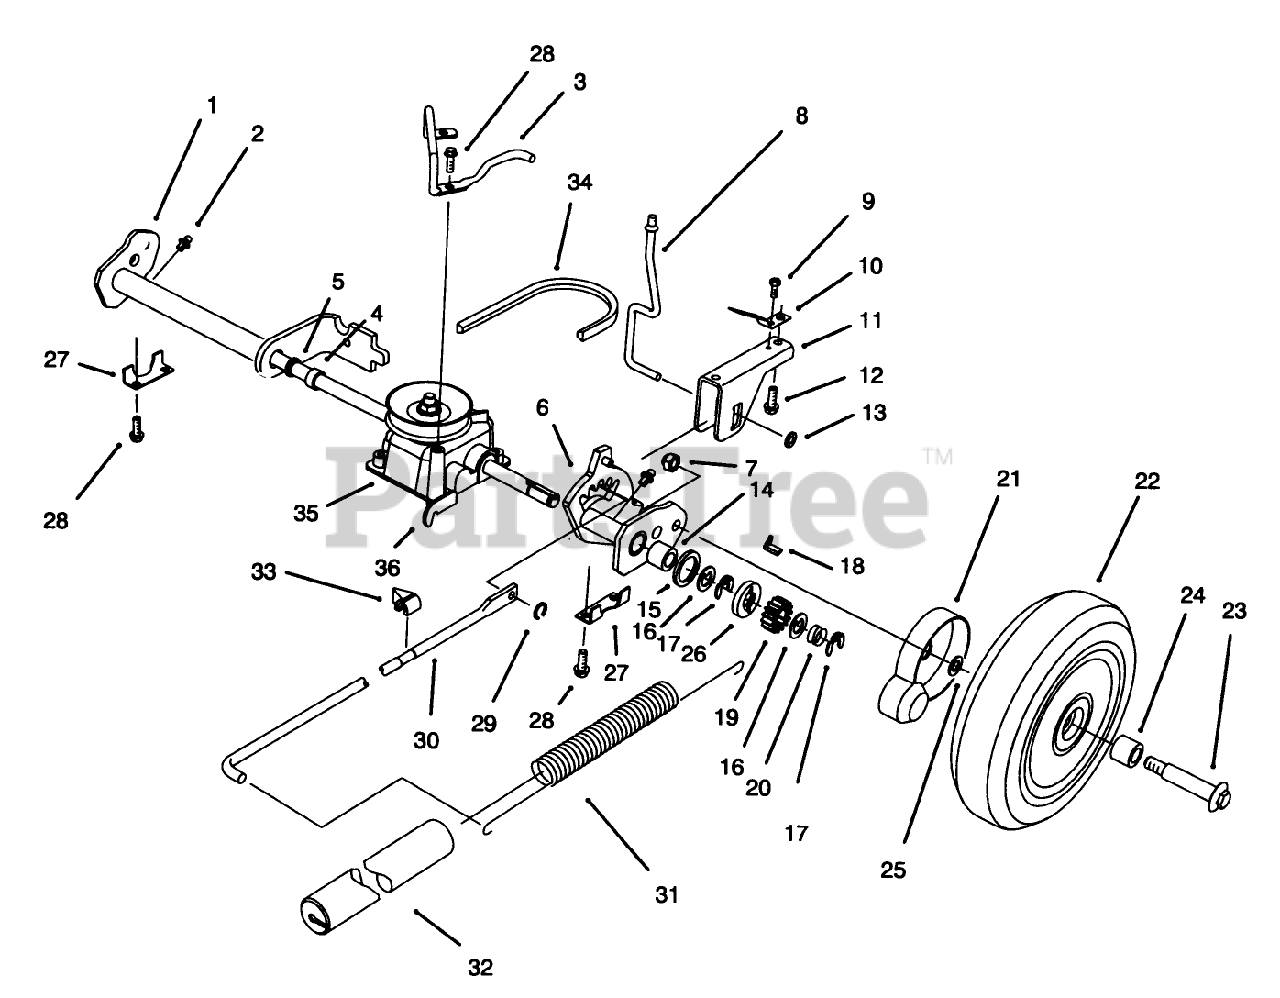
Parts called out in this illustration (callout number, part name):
1	ASM - RH PIVOT ARM
2	FITTING-GREASE
4	BUSHING
5	SEAL-OIL
7	NUT-HEX
8	TRIGGER ROD
9	SCREW 8 - 32 X 250
11	SADDLE - HOC
12	SCREW
13	PUSHNUT
15	RING-FRICTION
16	WASHER-THRUST, KEYED
17	RING-RETAINING,CLIP
18	KEY-ROCKING, LH
19	GEAR-PINION
20	SPRING-COMPRESSION
21	COVER-WHEEL
22	WHL & TIRE ASSEMBLY
23	BOLT-WHEEL
24	BUSHING
25	SPACER-COVER, WHEEL
26	WASHER-CLUTCH
28	SCREW-HWH
29	GRIP RING
30	LINK ROD
31	SPRING-COUNTERBALANCE
32	COVER-SPRING
33	INDICATOR-HEIGHT OF CUT
34	V-BELT
